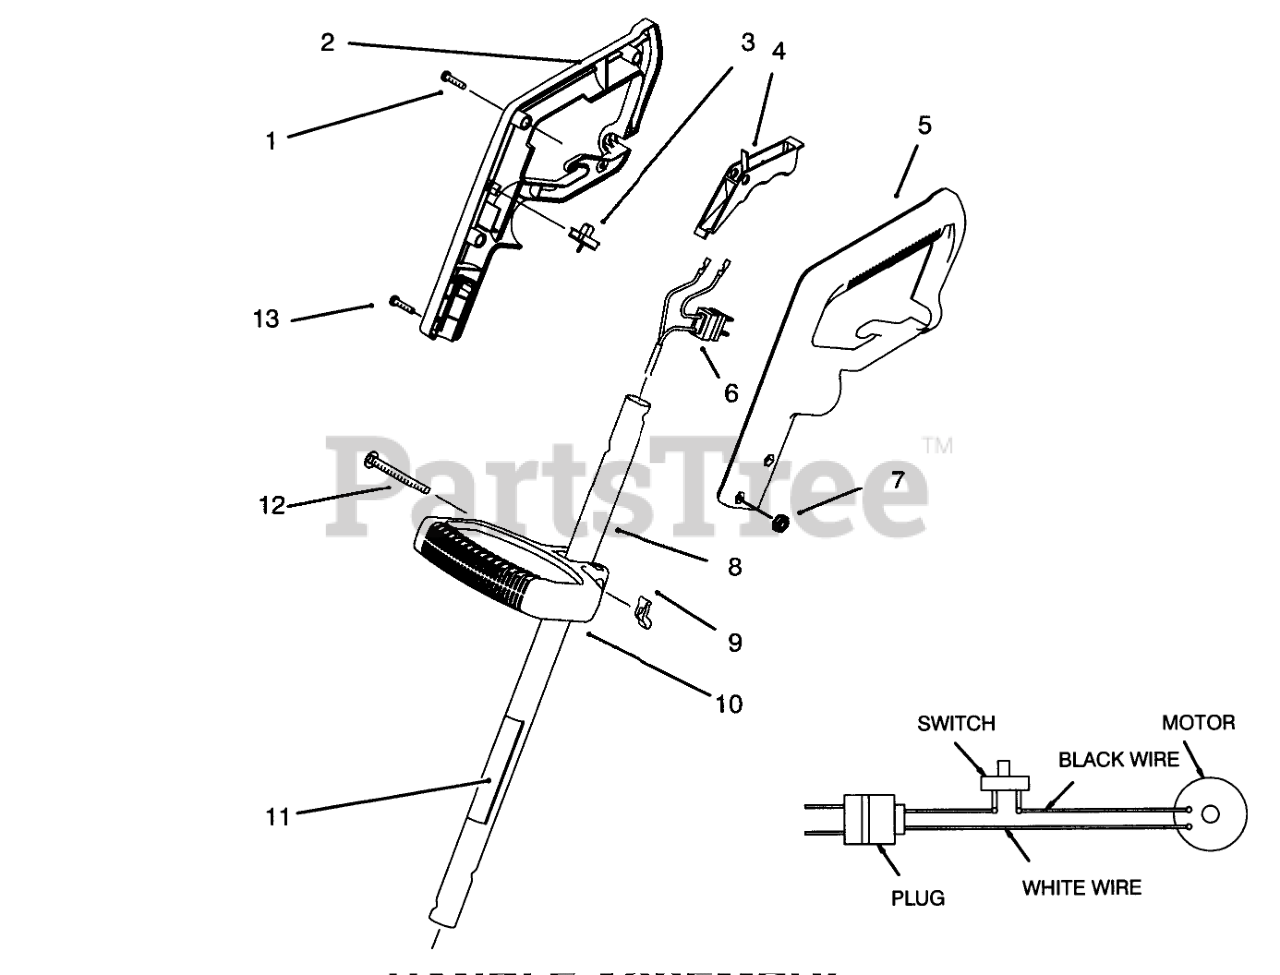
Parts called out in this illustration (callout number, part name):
1	Screw
2	HAND GRIP R.H.
3	SWITCH
4	TRIGGER
5	HAND GRIP L.H.
6	WIRING HARNESS
7	NUT-HEX
8	Tube Assembly (Incl. Ref. #11)
9	1/4"-20 STAMP WNG NUT
10	MID HANDLE
11	Decal-Safety
12	SCREW-CARR.25-20 X 2.50
13	SCREW-PPH
